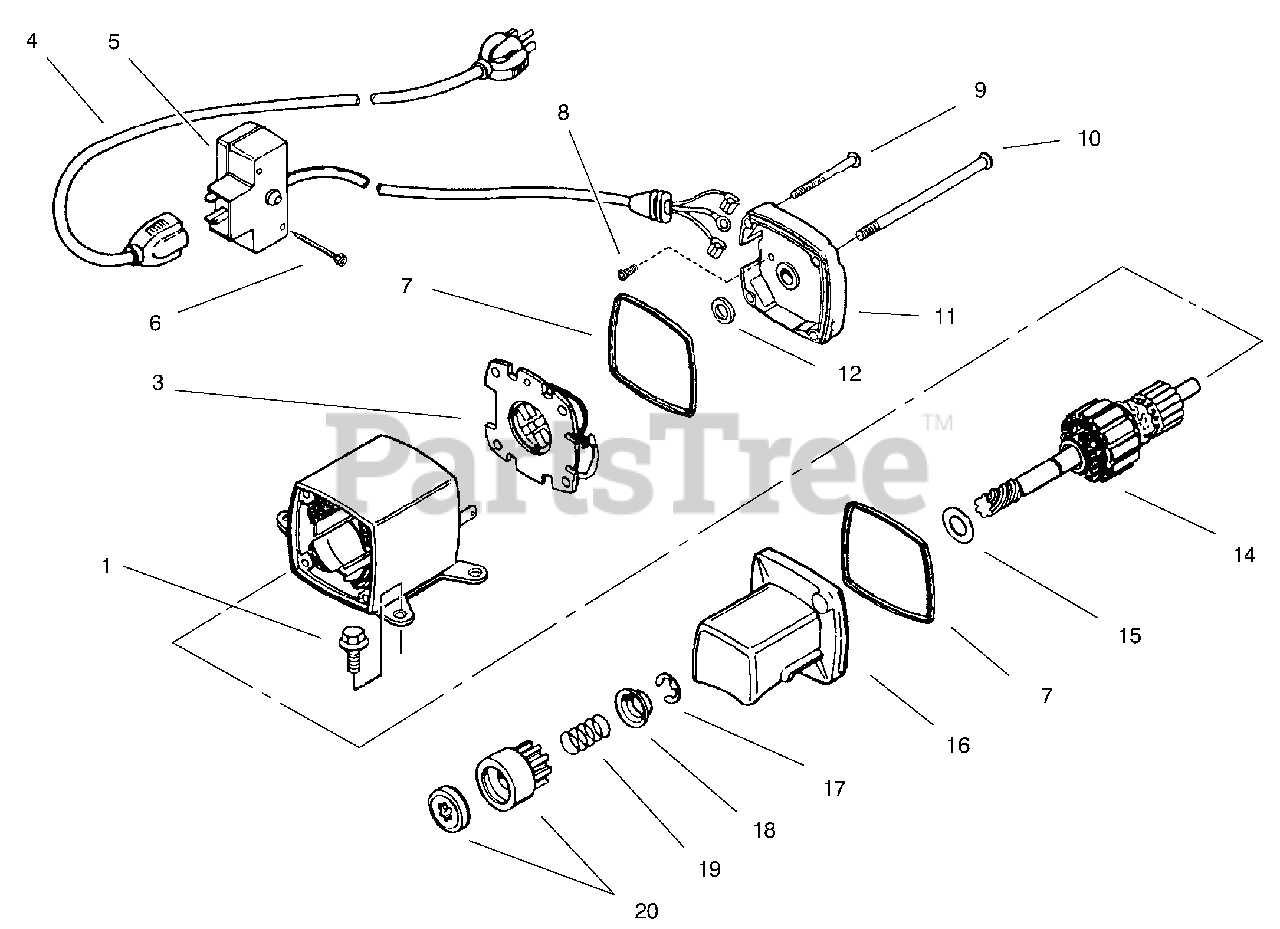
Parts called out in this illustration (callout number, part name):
1	Screw-Torx
3	Brush & Spring Card Asm
4	Cord-Extension
5	Switch Box Asm (Incl. Ref. # 6)
6	Screw
7	"O' Ring
8	Screw-Ground
9	Scerw-Ground
10	Bolt-Case
11	Cap-Commutator End Asm (Incl. Ref. #7)
12	Washer-Thrust
14	Armature
15	Washer-Thrust
16	Cap-Drive End (Incl. Ref.# 7)
17	Ring-Retainer
18	Retainer-Spring
19	Spring-Anti Drift
20	Nut & Gear
